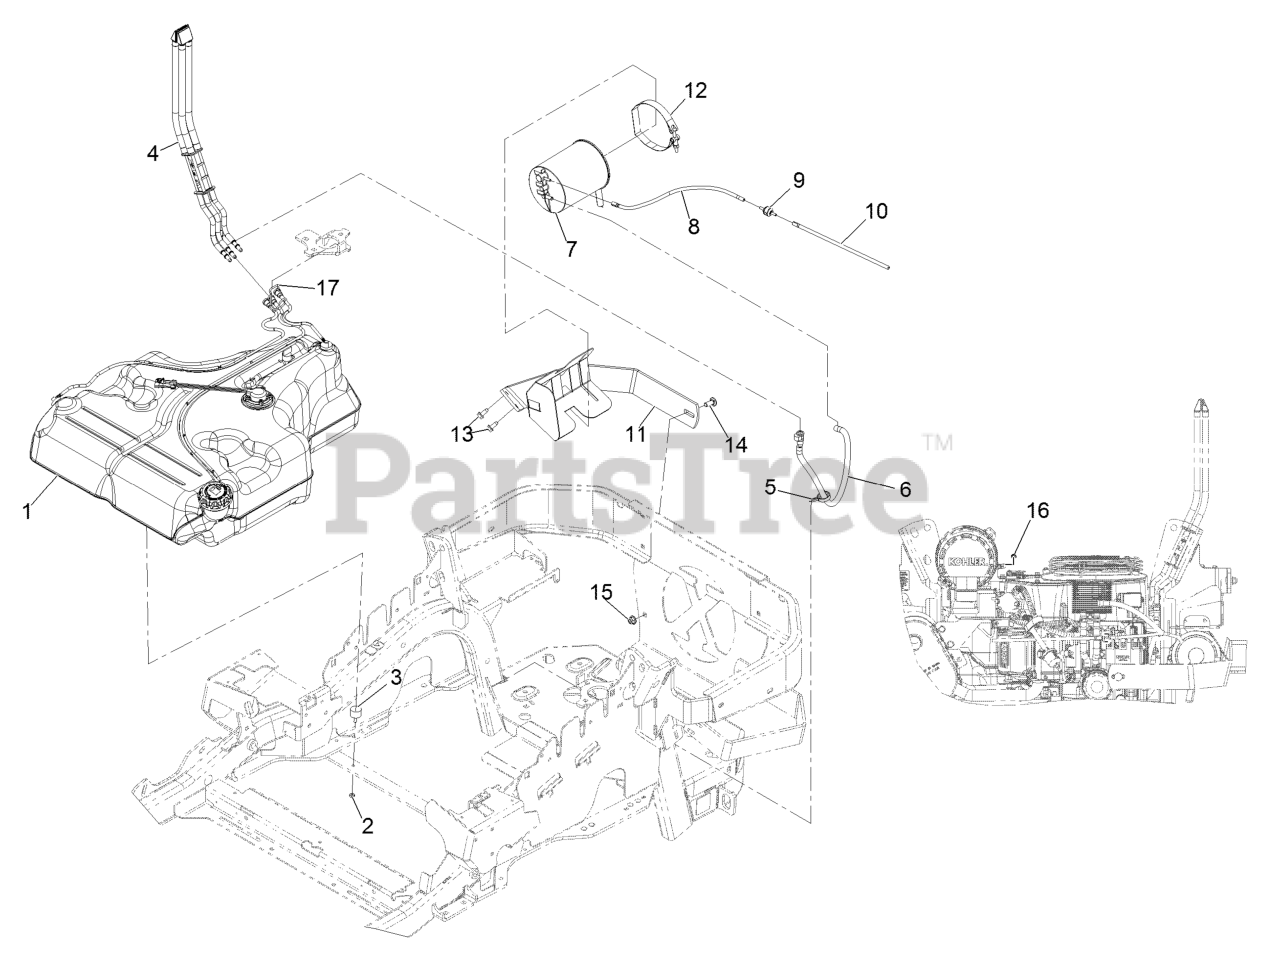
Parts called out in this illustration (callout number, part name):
2	NUT-JAM
4	FUEL MANIFOLD VENT ASM
5	CLAMP-HOSE
6	VENT HOSE ASM
7	CANISTER-CARBON, 1200CC
8	HOSE-VENT, FORMED
10	HOSE-VENT, FORMED
11	MOUNT-CANISTER
12	CLAMP, T-BOLT
13	Screw-HWH 5/16-18 X 3/4 Tf
14	SCREW-CARR
15	NUT-HF, NI
16	PLUG-PORT
17	RETAINER-LINE, VAPOR
